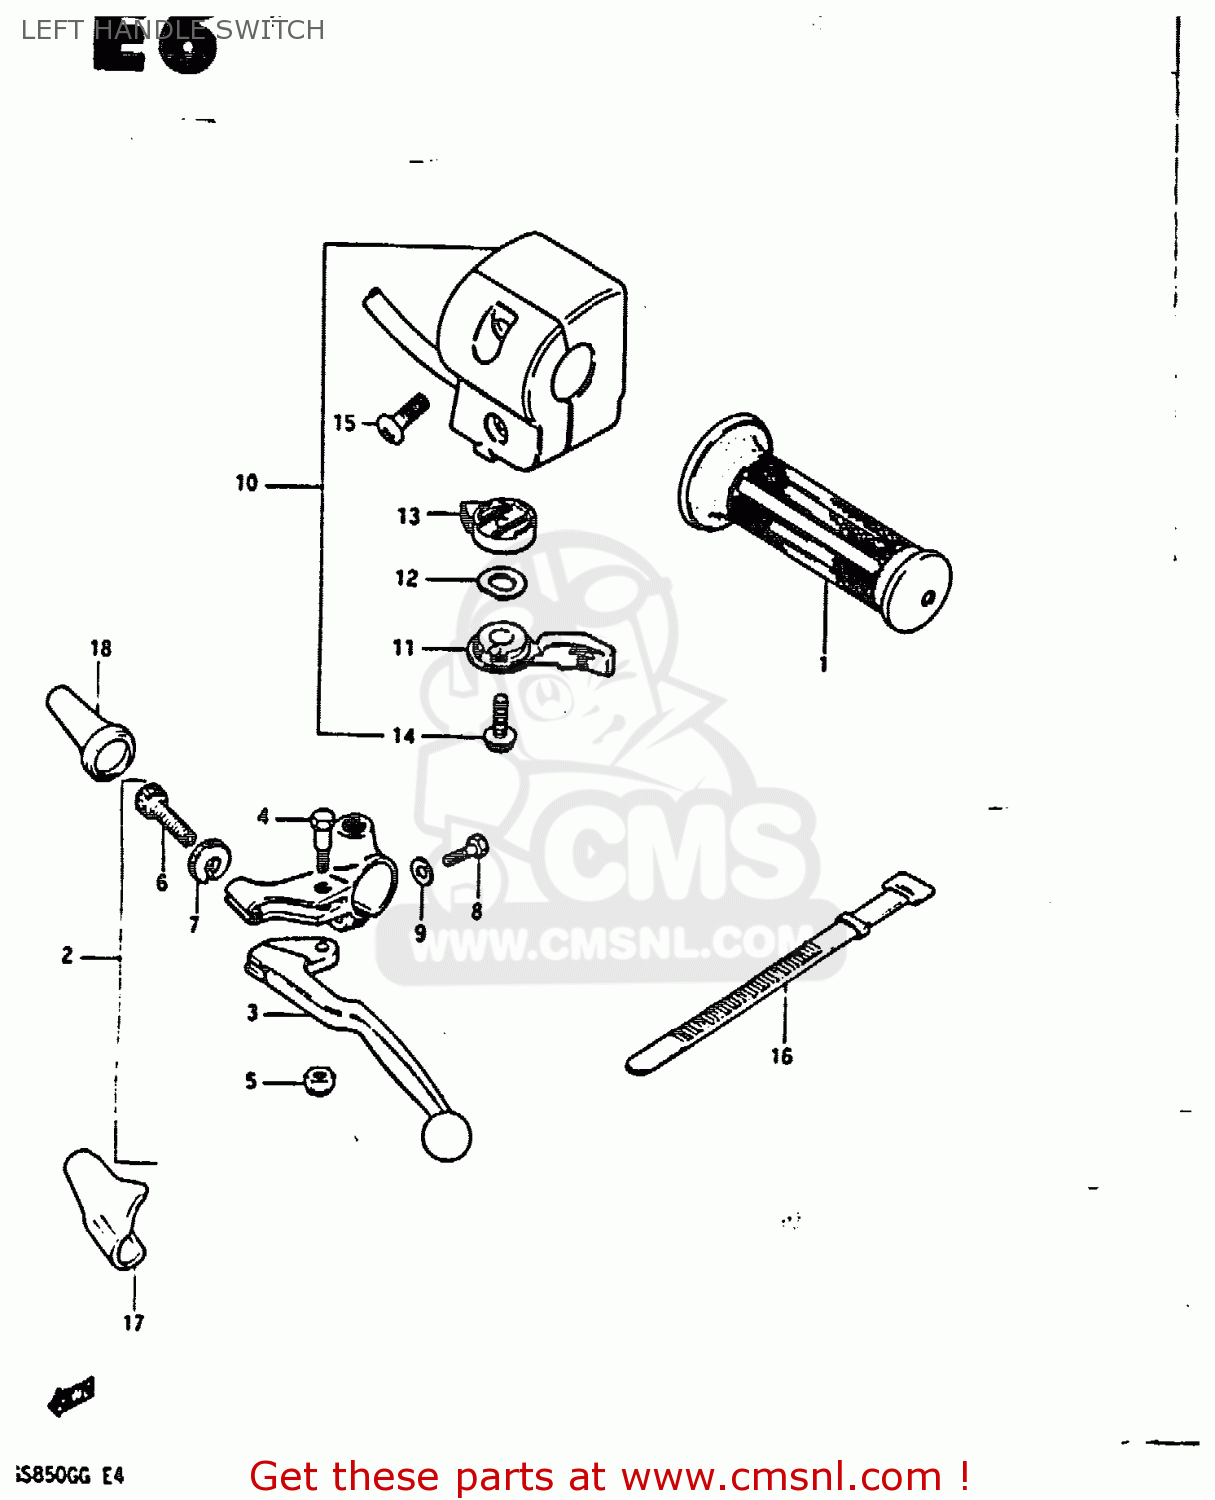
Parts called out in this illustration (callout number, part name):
1	GRIP,L
2	LEVER ASSY, CLUTCH
3	LEVER,CLUTCH
4	BOLT,LEVER PIVOT
5	NUT
6	ADJUSTER,CABLE
7	NUT,CABLE ADJUSTER
8	BOLT
9	WASHER
10	SWITCH ASSY, HANDLE LH (NEUTRAL)
11	LEVER,STARTER
12	WASHER,ADJUSTER
13	BODY,STARTER LEVER
14	SCREW,CHOKE LE
15	SCREW
16	CLAMP(L:120)
17	COVER,CLUTCH LEVER
18	BOOT,CLUTCH CABLE
